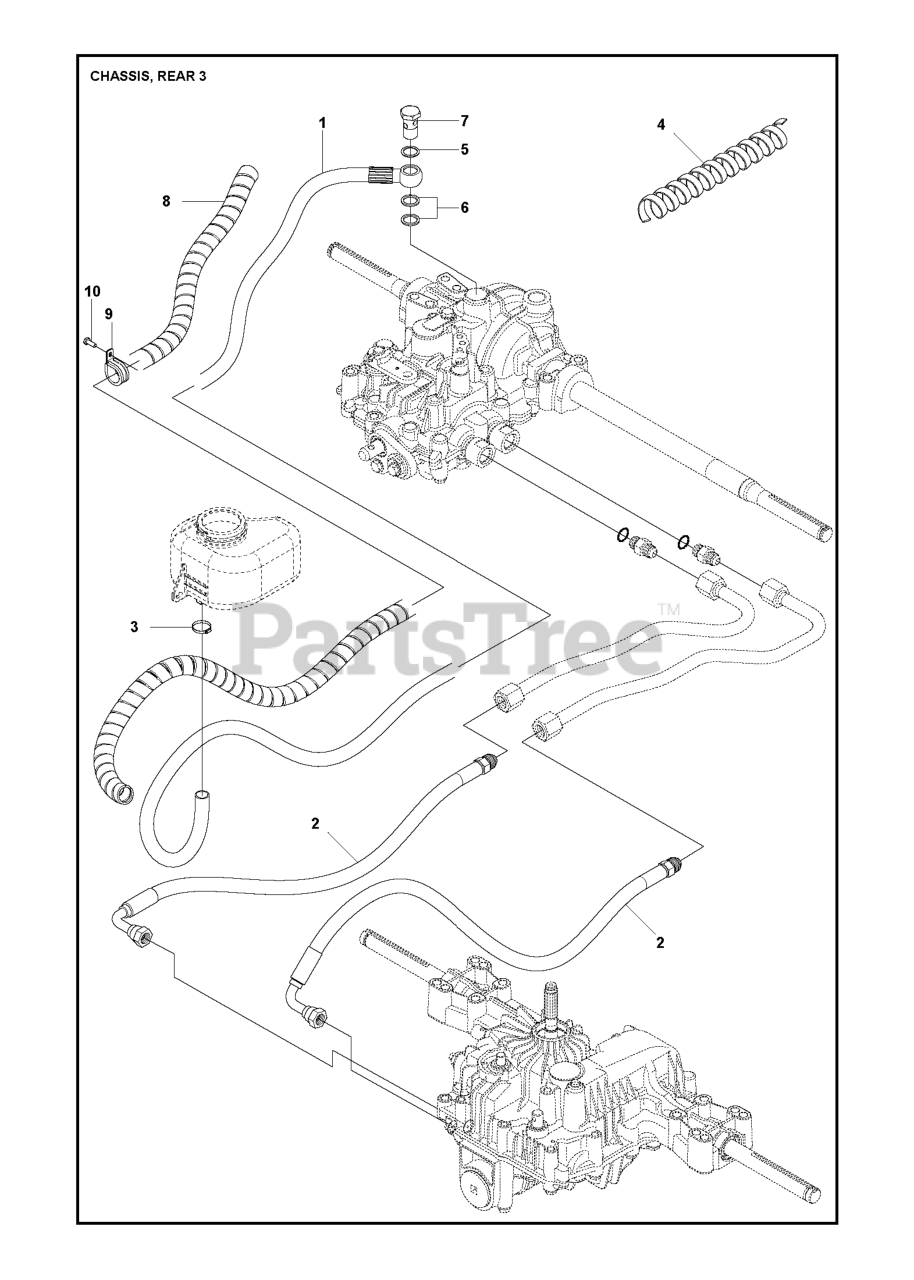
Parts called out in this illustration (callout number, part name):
1	HYDRAULIC HOSE
2	HYDRAULIC HOSE
3	HOSE CLAMP 20-32
7	PIPE FITTING
8	HOSE GUARD
9	HOSE CLAMP
10	SCREW
